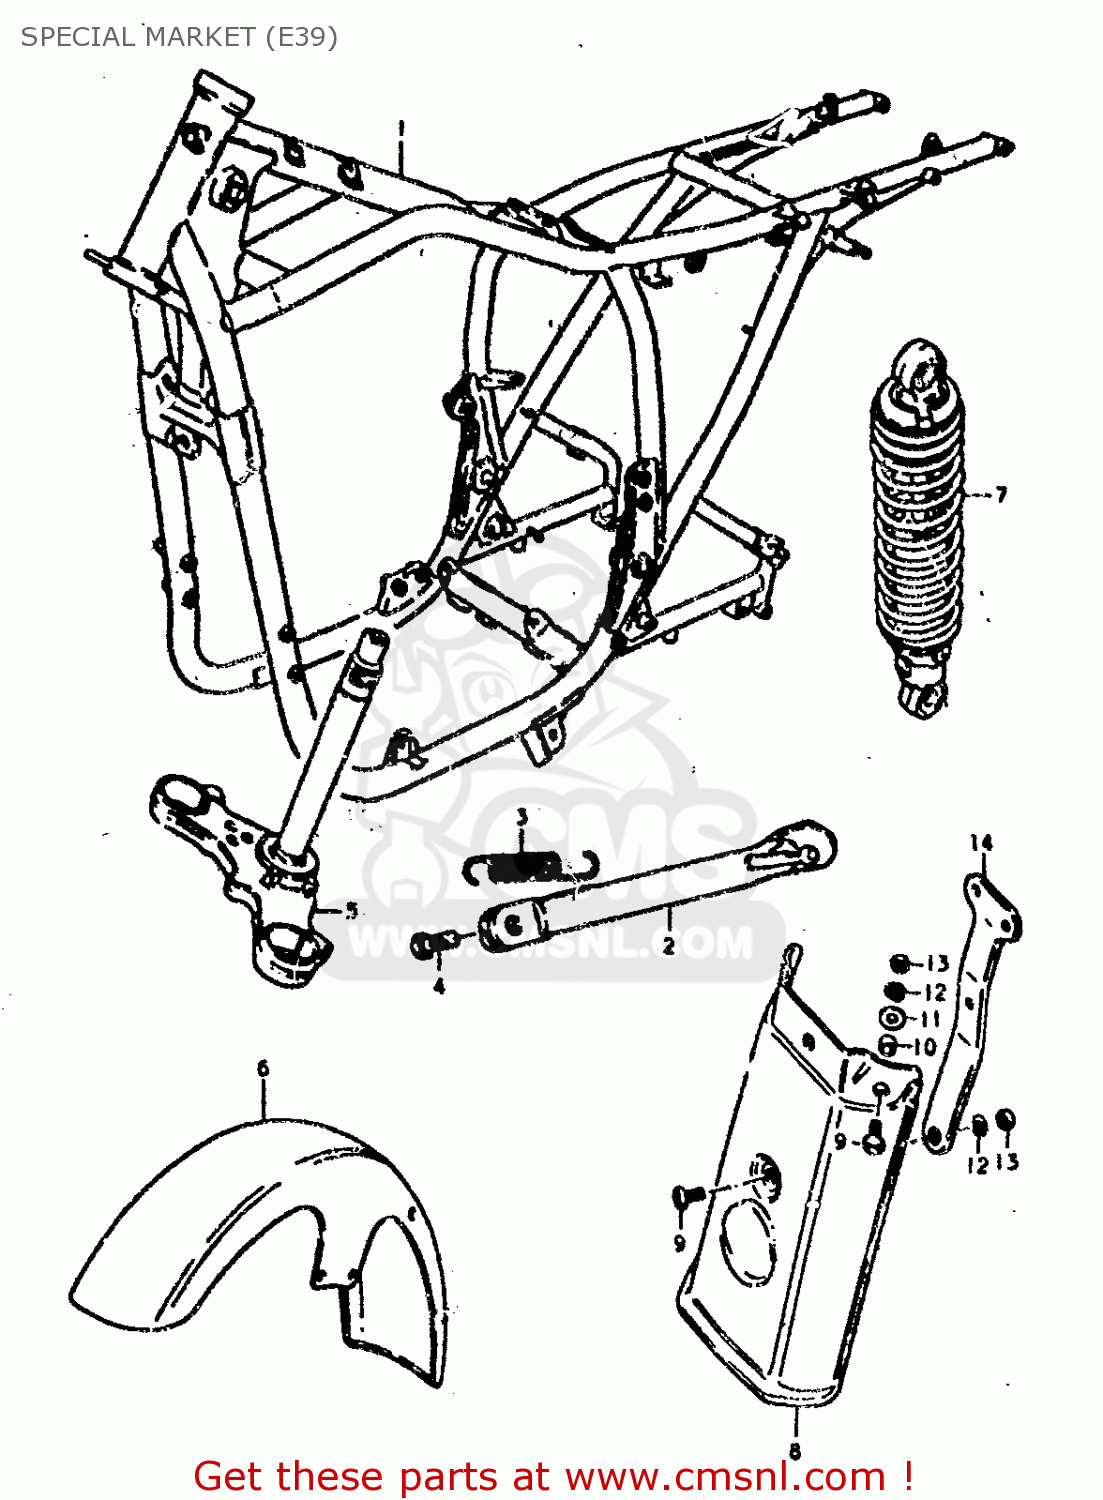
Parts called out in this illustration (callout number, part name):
1	FRAME
2	STAND,PROP
3	SPRING
4	BOLT
5	STEERING STEM
6	FENDER,FR
7	SHOCK ABSORBER, REAR
8	EXTENSION,REAR FENDER
9	SCREW (6X15)
10	SPACER(6.2X8.3X5.7)
11	WASHER(6.5X18X1)
12	LOCK WASHER
13	NUT
14	FENDER,REAR
